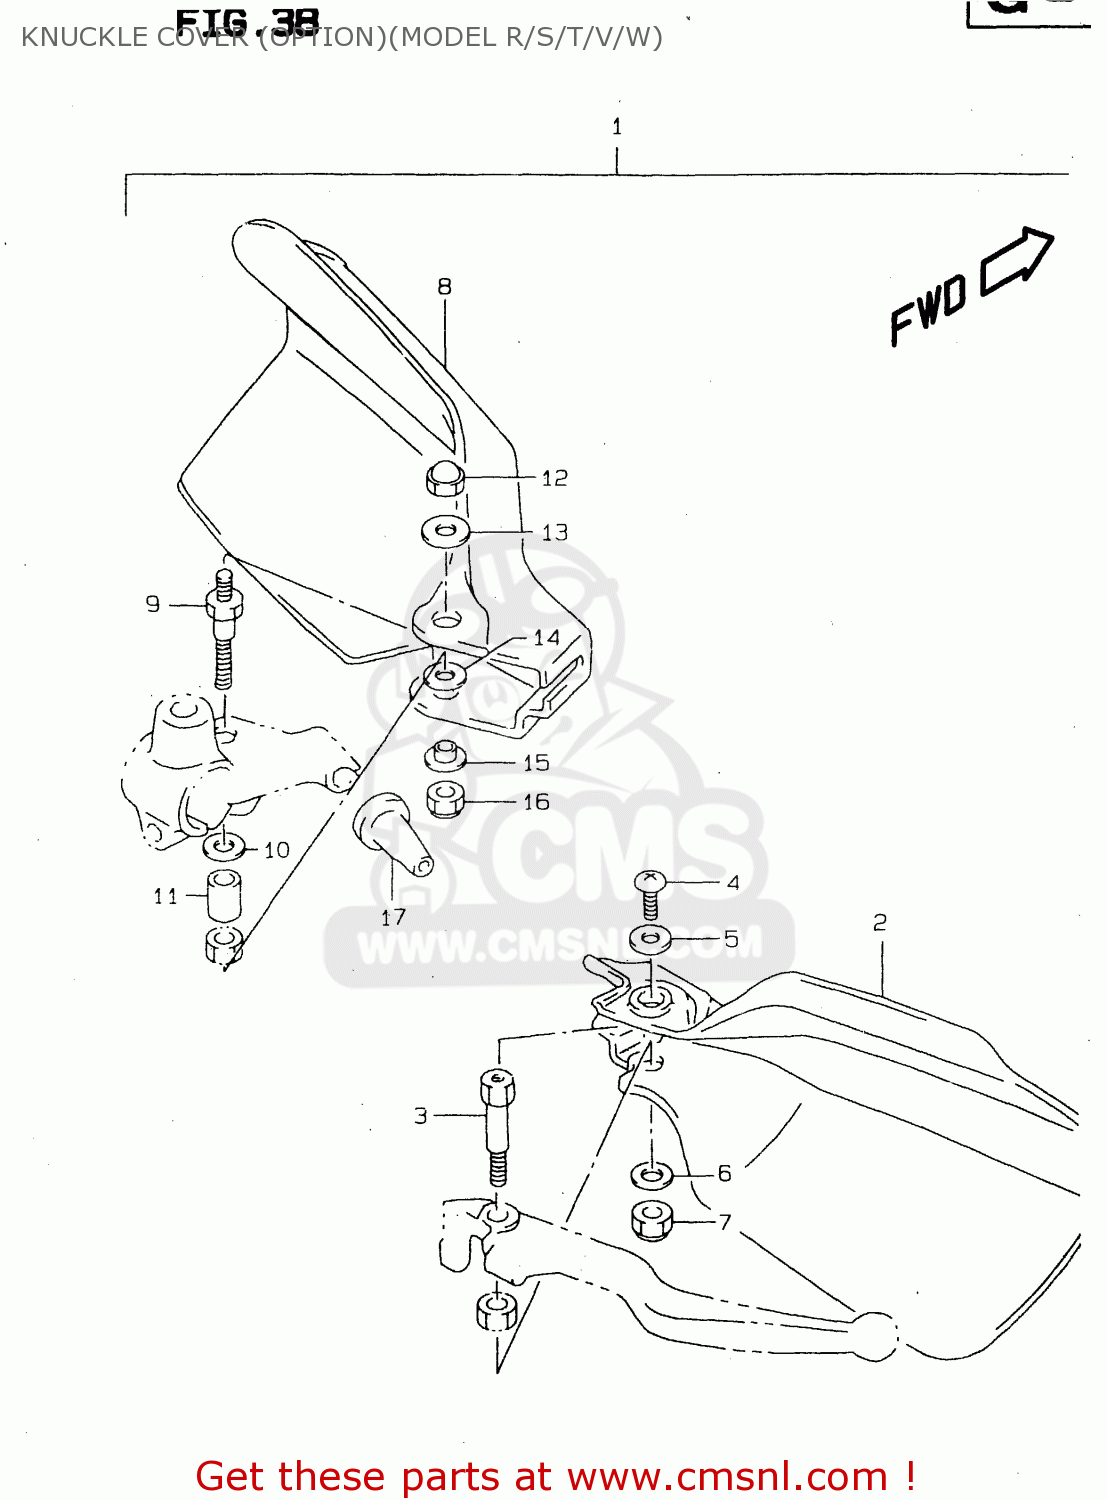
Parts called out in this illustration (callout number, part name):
1	COVER SET,KNUCKLE
2	COVER,KNUCKLE,R
3	BOLT,BRAKE LEVER PIVOT
4	SCREW
5	WASHER(5.5X16X1.2)
6	WASHER(6.5X16X1.6)
7	NUT 6MM
8	COVER,KNUCKLE,LEFT
9	BOLT,LEVER SET
10	WASHER,LEVER SET
11	SPACER,LEVER SET
12	NUT
13	WASHER(6.5X20X1.6)
14	WASHER(6.5X16X1.2)
15	WASHER
16	NUT 6MM
17	BOOT,CLUTCH CABLE
